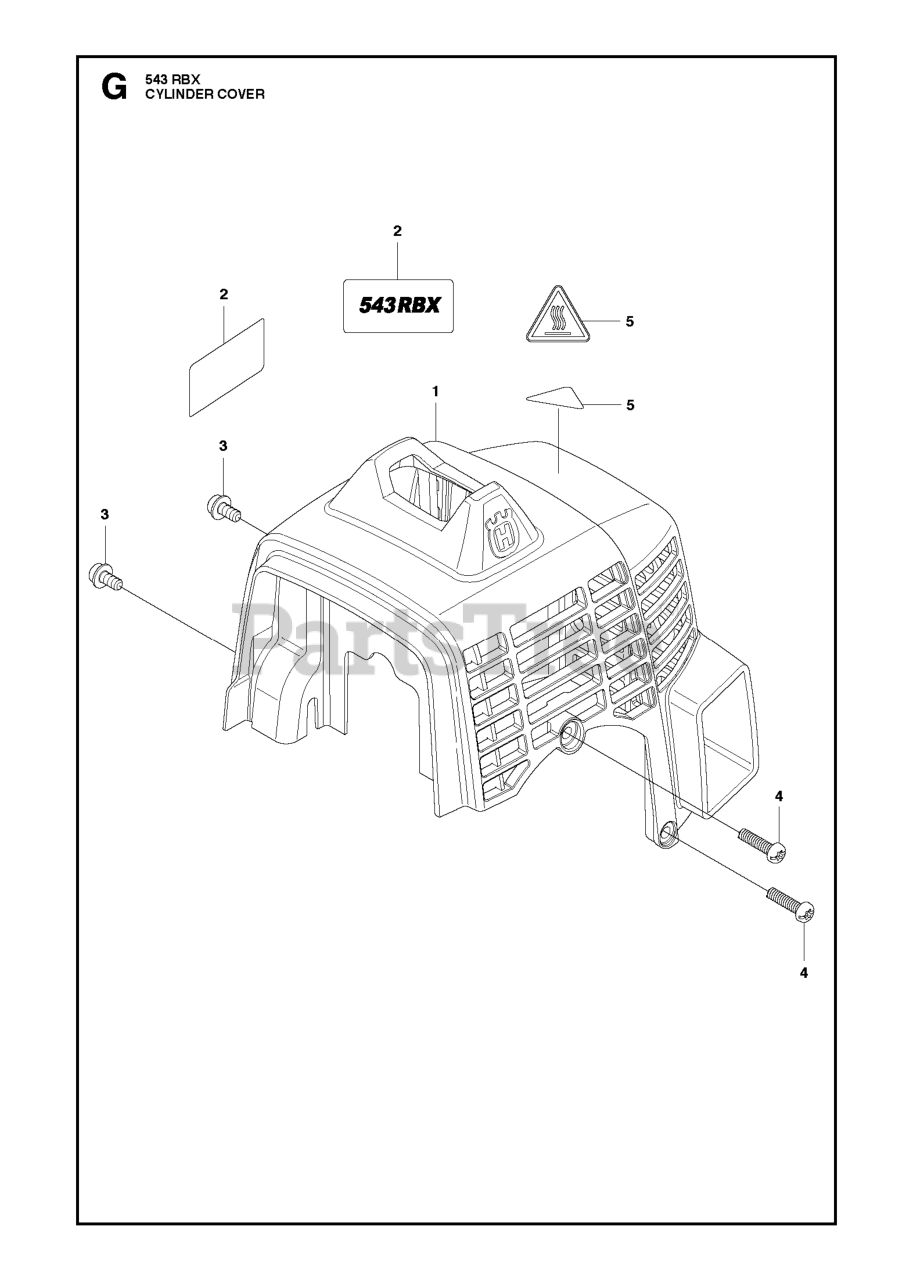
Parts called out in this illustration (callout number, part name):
1	COVER ENGINE
3	BOLT (RPLS T495051010-11)
4	SCREW, TORX (RPLS T4970-52001)
5	LABEL HOT CAUTION
